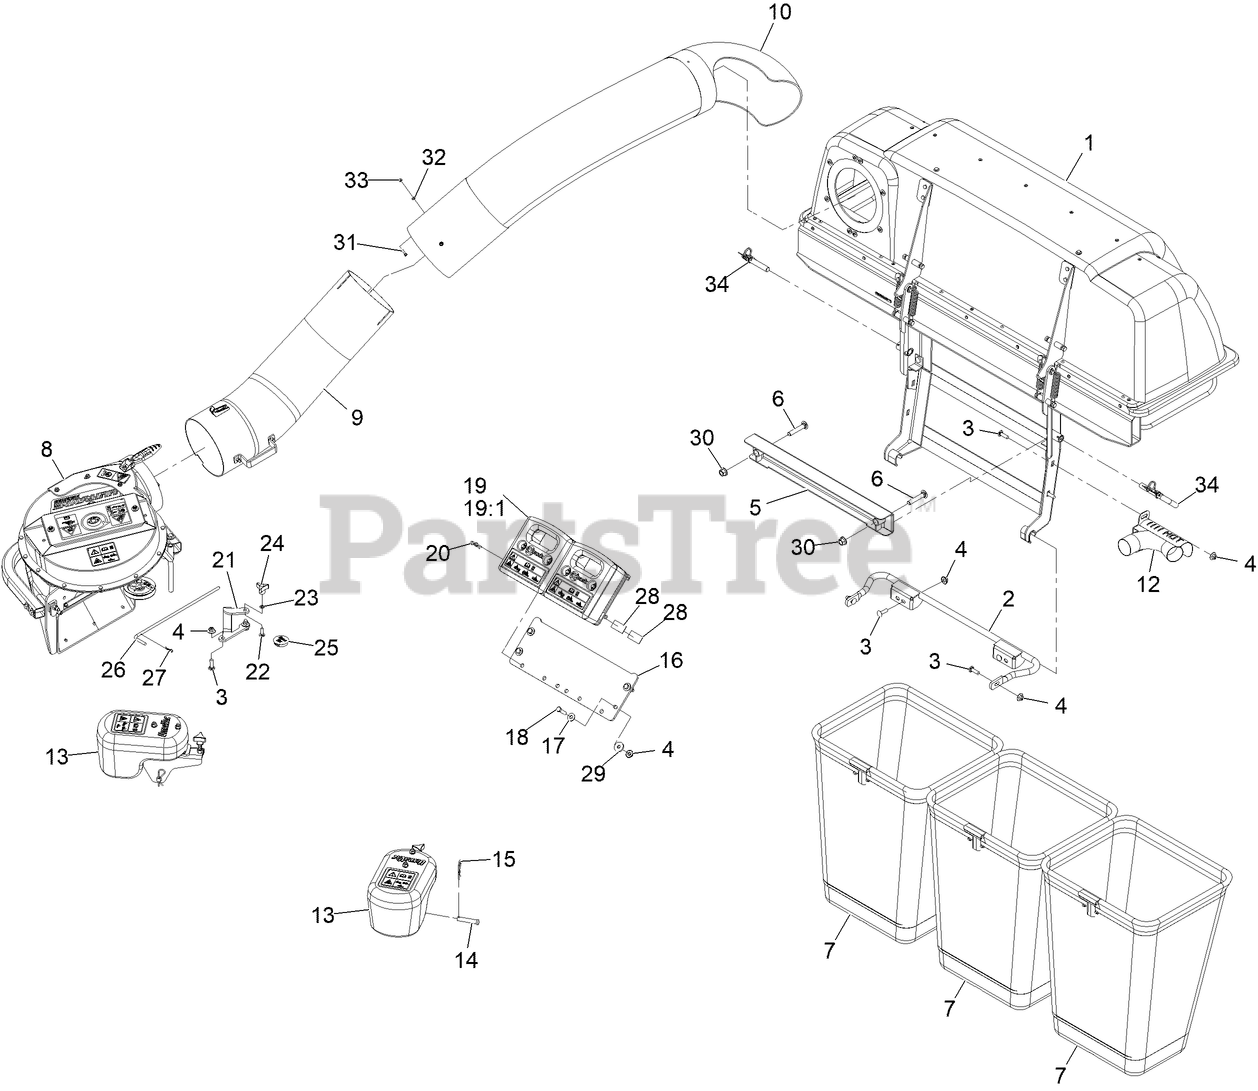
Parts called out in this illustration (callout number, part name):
1	ASM,Hood Uv 3 Bag
2	MOUNT-BAGGER, LOWER
3	Bolt-Carriage 3/8-16 X 1 1/4
4	Nut-Nyloc 3/8-16 Flg
5	MOUNT-BAGGER, UPPER
6	SCREW-CARR
7	BAG AND FRAME ASM
8	ASM, BLOWER LARGE - SVC ONLY
9	LOWER TUBE ASM
10	TUBE-UPPER
12	EXHAUST DIVERTER ASM
13	ASM,CASTER WEIGHT
14	PIN-CLEVIS
15	PIN-HAIR
16	PLATE,WEIGHT ASM MOUNT
17	WASHER-FLAT
18	SCREW-HH
19	ASM,CAST WEIGHT
19:1	DECAL-WARNING WEIGHT
20	PIN-HAIR
21	BRACKET,BELT COVER
22	BOLT-CARR
23	RING-RETAINING, BOLT
24	KNOB-3 PRONG
25	PLUG, BLACK NYLON 1.75
26	PIN,CHUTE PIVOT
27	PIN-COTTER
28	PAD-RUBBER
30	Nut-Lock 1/2-13
31	SCREW-HWH
32	WASHER-FLAT
33	NUT-LOCK, NI
34	PIN-MOUNT, BAGGER
